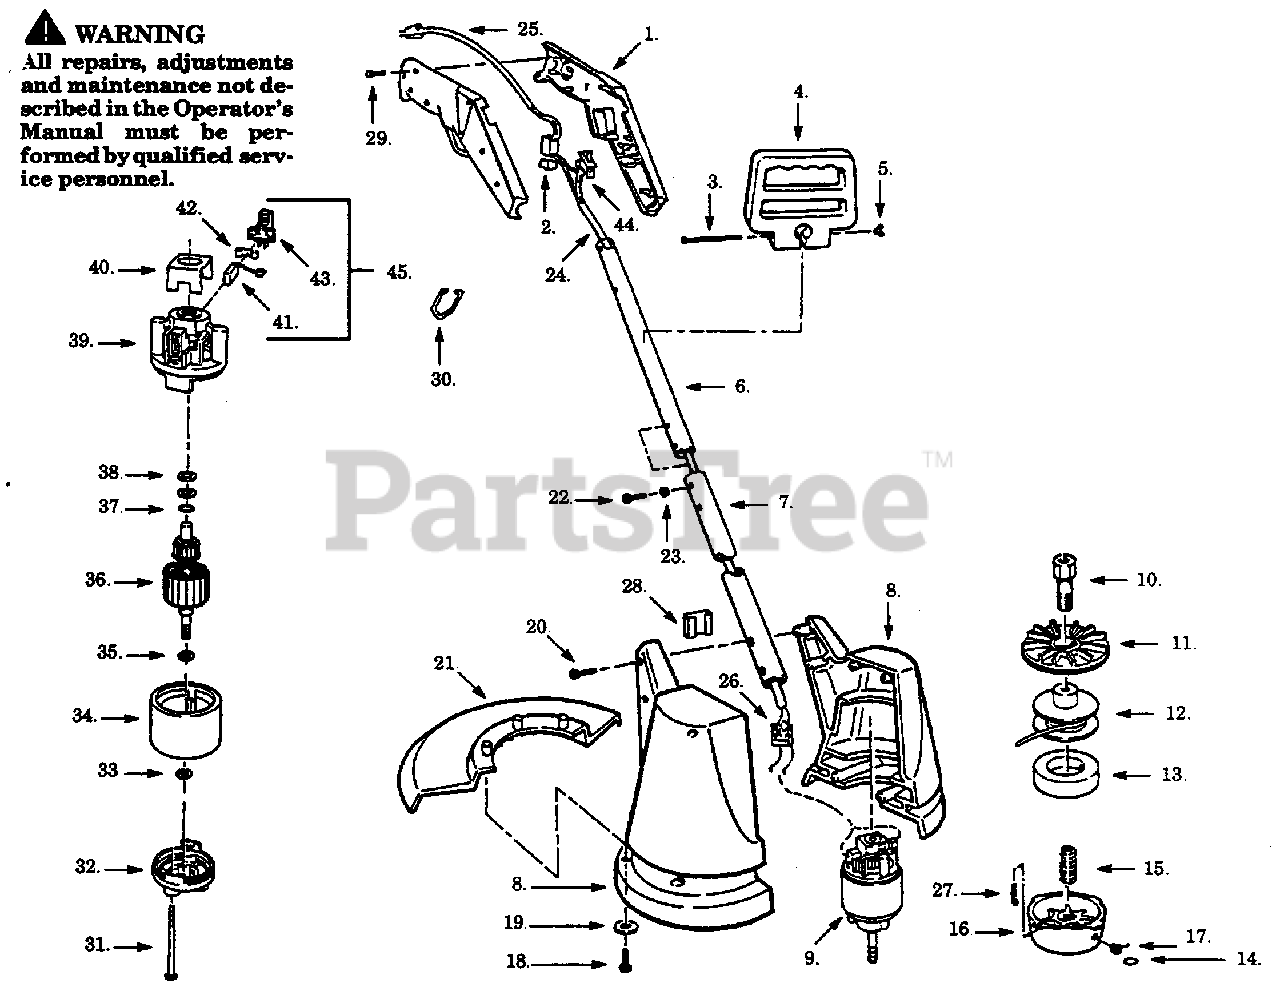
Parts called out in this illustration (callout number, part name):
1	R.H./L.H. Handle
2	Trigger Switch
4	Side Handle
5	Wing Nut
6	Upper Handle Tube
7	Lower Handle Tube
8	R.H./L.H. Housing
10	Drive Adapter
11	Rear Plate
12	Spool & Line
13	Foam Pad
14	Retaining Ring
21	Line Cutter Guard
25	Power Cord
26	P.C. Bridge Kit
27	Cotter Pin
28	Insulating Shield
32	Endbell Output
34	Field Ass'y.
35	Retainer Ring
36	Armature
37	Retainer Ring
39	Endbell (Brush)
40	Insulator
43	Brush Holder
44	Power Switch
45	Brush Kit (Incl. 41,42,43)
